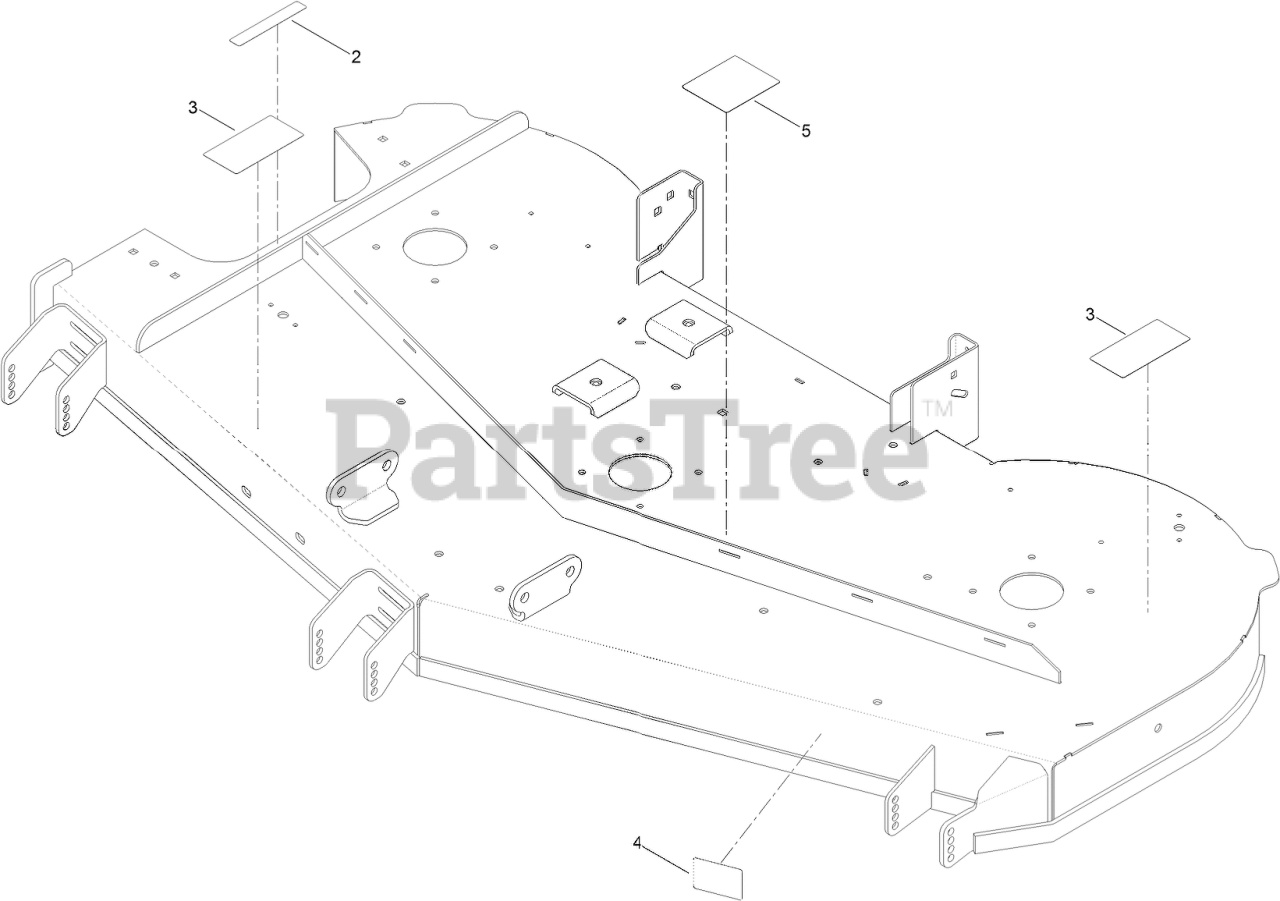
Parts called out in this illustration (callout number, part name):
2	DECAL-DANGER
3	DECAL-DANGER, DECK
4	DECAL-SCALP, ANTI
5	DECAL-ROUTING, BELT
